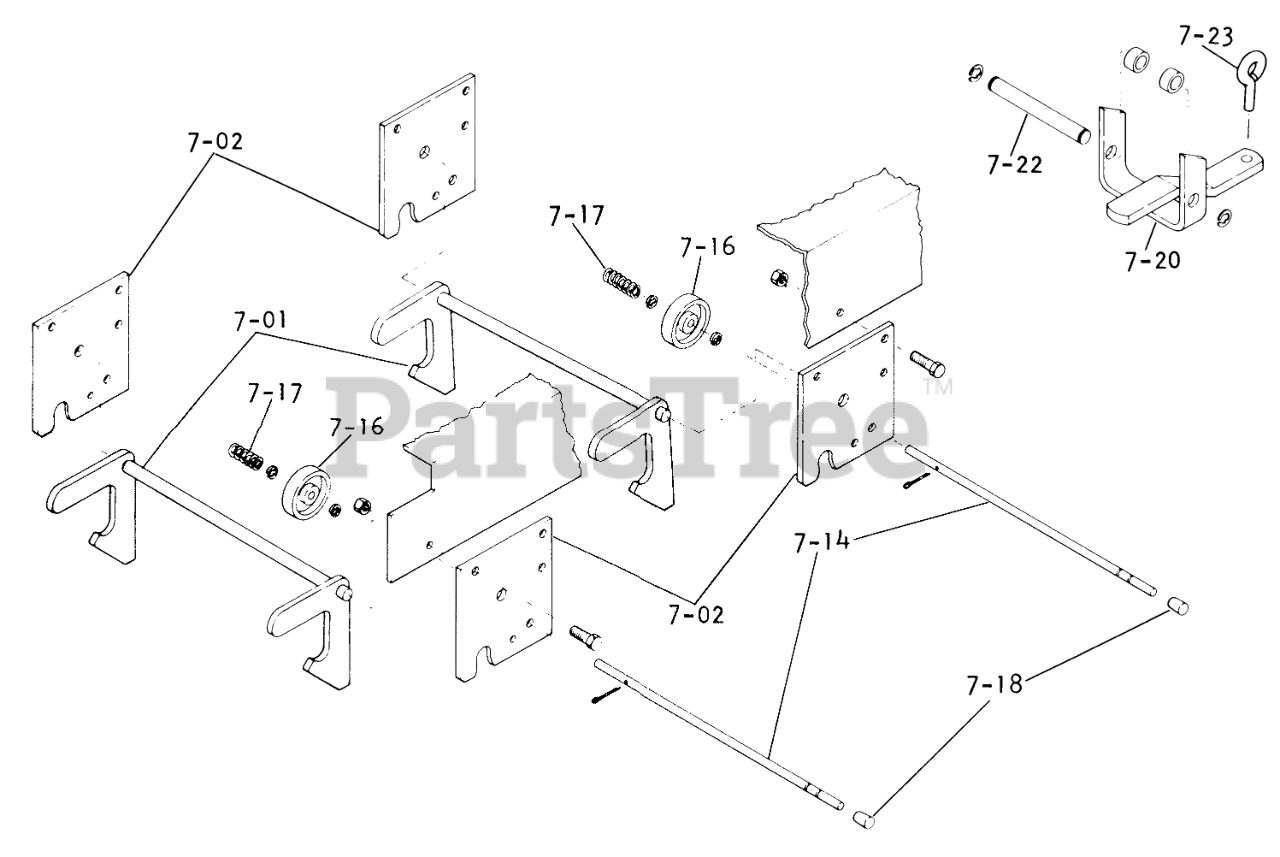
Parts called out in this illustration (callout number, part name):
7-01	Assy-Latch
7-02	Hitch Plate
7-14	Rod Lock
7-17	SPRING-COMPRESSION
7-18	Cap
7-20	Hitch
7-22	Pin
7-23	Pin-Tool
